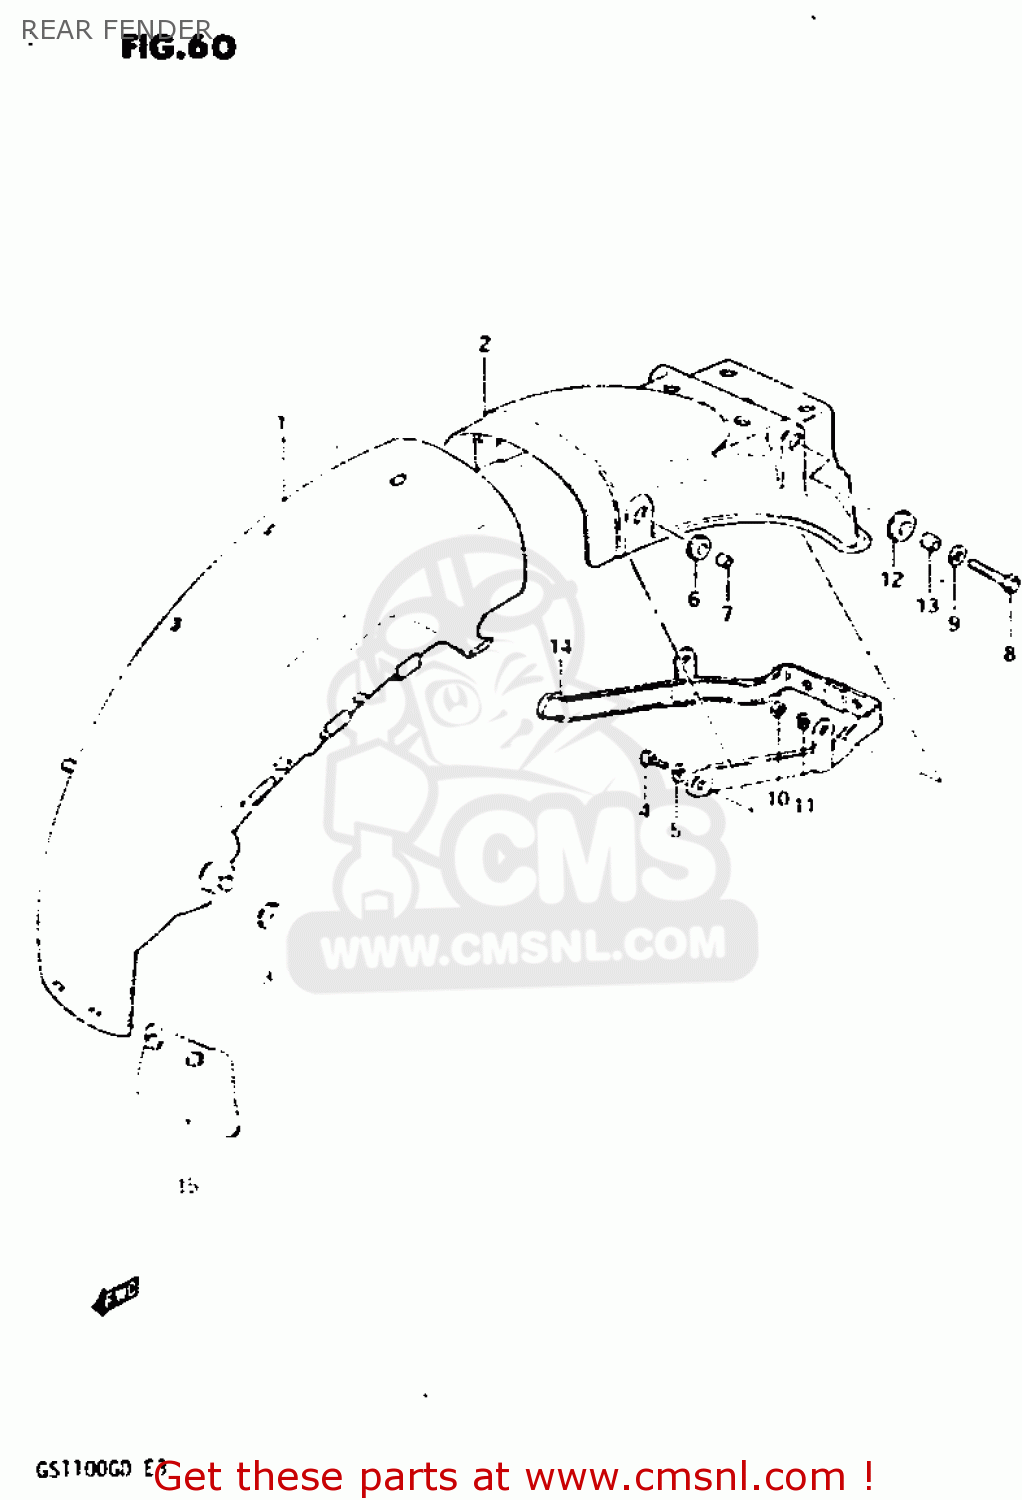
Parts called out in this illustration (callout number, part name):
1	BODY,RR FENDER FR
2	FENDER,REAR
3	CUSHION
4	BOLT
5	WASHER,LOCK
6	CUSHION
7	SPACER(6.1X9X7.5)
8	BOLT
9	WASHER
10	NUT
11	LOCK WASHER
12	CUSHION
13	SPACER (8.2X12X7.5)
14	REINFORCEMENT,REAR FENDER
15	GUIDE,RR FENDER MUD
